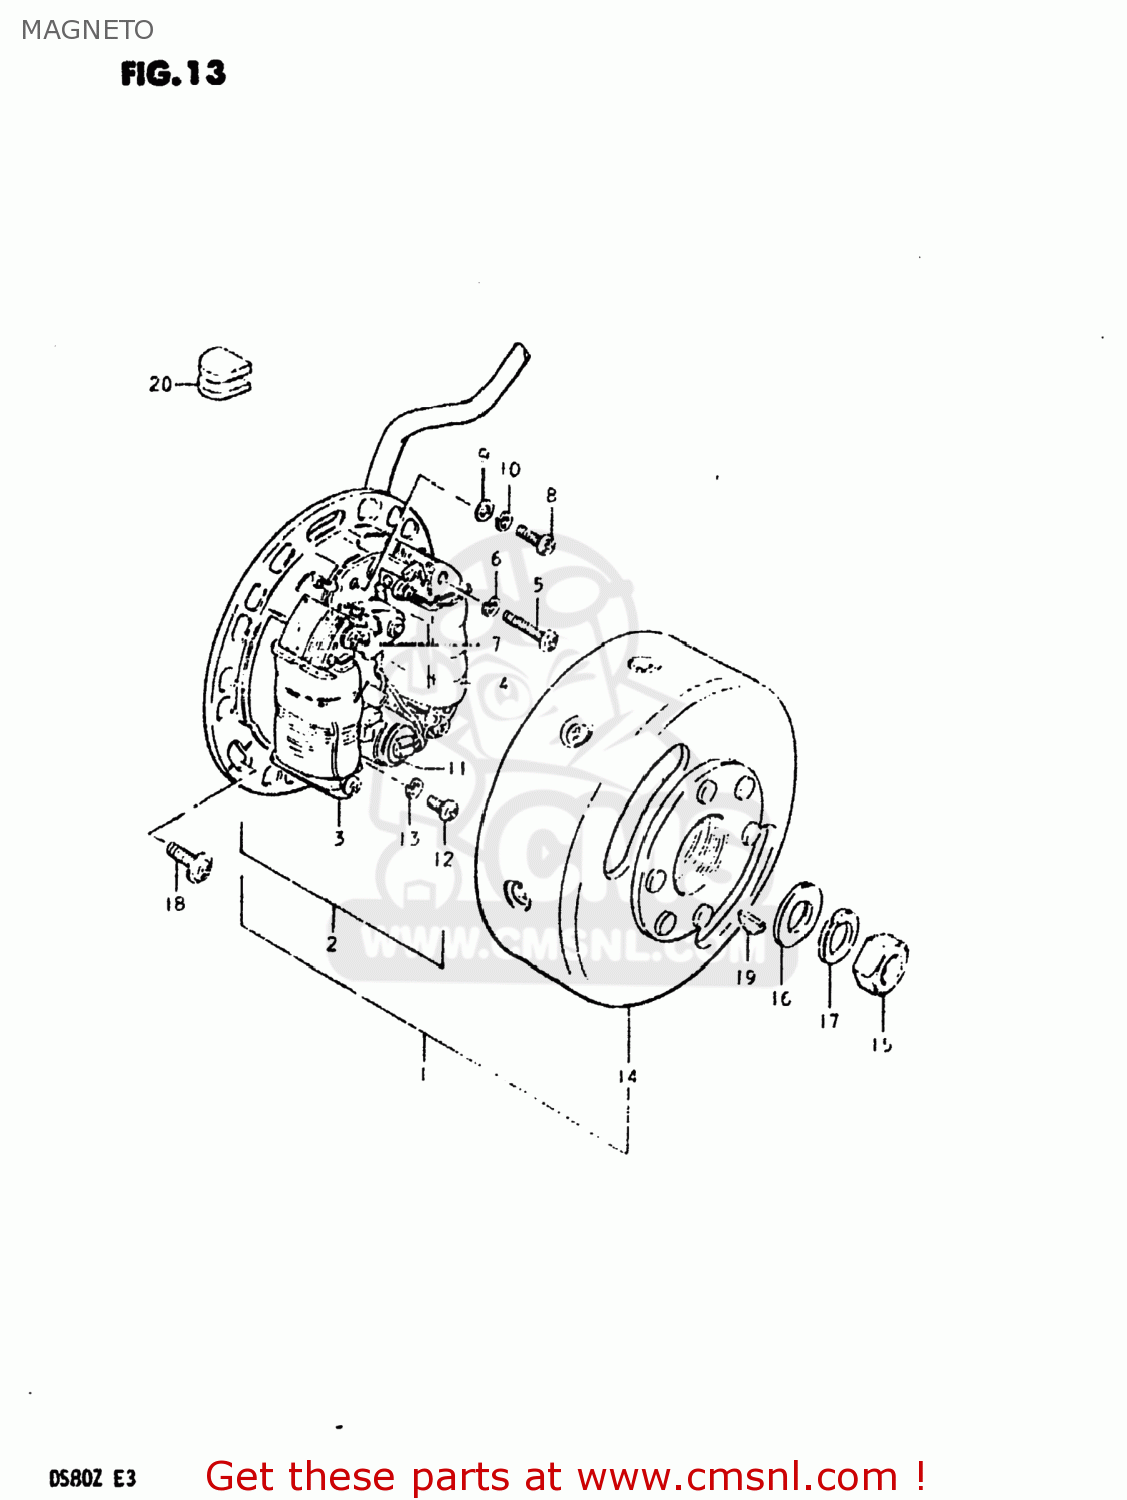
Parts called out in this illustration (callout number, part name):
1	MAGNETO ASSEMBLY
2	STATOR ASSEMBLY
3	COIL,LIGHTING
4	COIL,PRIMARY
5	SCREW (4X30)
6	LOCK WASHER
7	POINT ASSY,CONTACT
8	SCREW(4X10)
9	WASHER
10	LOCK WASHER
11	CONDENSER
12	SCREW
13	LOCK WASHER
14	ROTOR ASSEMBLY
15	NUT (10MM)
16	WASHER
17	LOCK WASHER
18	SCREW(5X14)
19	KEY
20	PLUG
